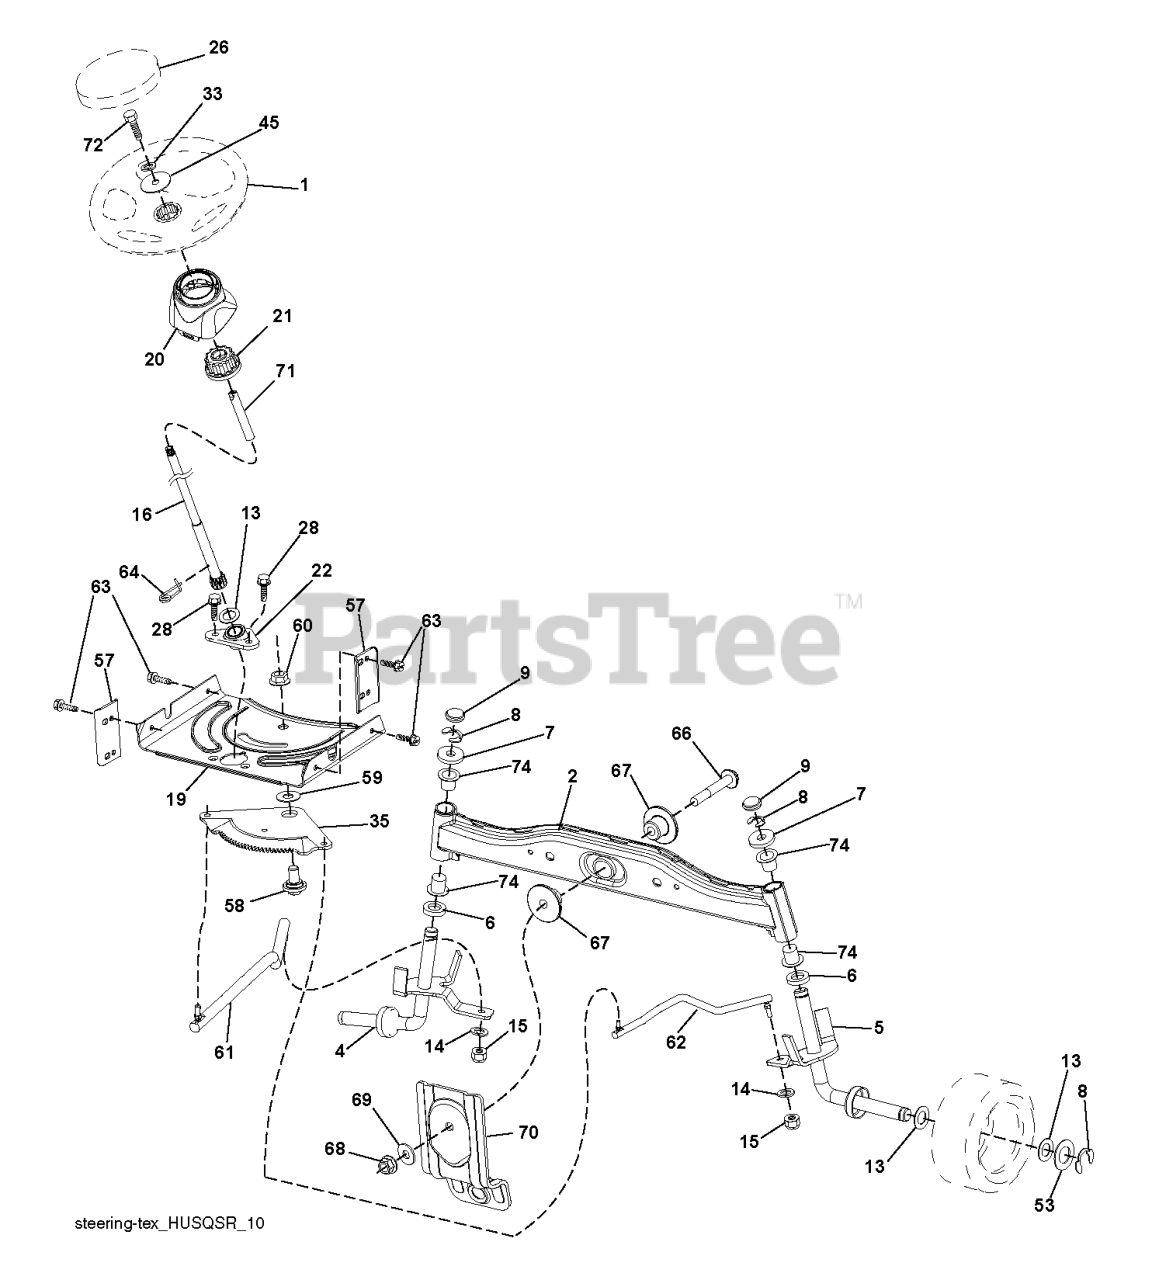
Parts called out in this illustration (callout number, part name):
1	RP WHEEL.STEER.HUSQ.PREM.OVMLD
2	AXLE HALF ASM-WELDED
4	SPINDLE.WELDED.LH.15"TEX
5	SPINDLE.WELDED.RH.15"T
6	THRUST WASHER
9	CAP.SPINDLE.BLACK
14	WASHER, LOCK 3/8
15	NUT CROWNLOCK 3/8-24
16	SHAFT STEERING
19	PLATE.STEER.DDL.NLT/NG
20	BOOT, STEERING
21	ADAPTER, WHEEL STNG..
22	STEERING.SUPT.LOWER.
26	RP INSERT.CAP.WHL.STRG.HUSQ.
28	SCREW, 3/8-16X3/4
33	WASHER.LOCK.HVY.HLCL.SPR.5/16
35	GEAR.SECTOR.PLATE.DDL.
45	WASHER.11/32
53	WASHER.HARDENED
57	BRACKET.UPSTOP.TEX
58	BOLT.SHOULDER.SECTOR.P
59	WASHER.THURST.SECTOR.S
60	NUT FLANGE LOCK 5/8-11
61	DRAGLINK.LH.BALLSTUD.D
62	DRAGLINK.RH.BALLSTUD.D
63	SCREW
64	RETAINER.CLIP.SPRING.S
66	BOLT HEX FGHD 7/16-14 X 3 SERR
67	BUSHING.PM.FRONT AXLE
68	NUT.LOCK.FLANGE.7/16
69	WASHER.1.5X.505X.118
70	BRKT.DECK.SUSPENSION.F
71	SHAFT EXTENSION STEERING
72	BOLT.FIN.HEX.5/16-18
74	BRNG T
